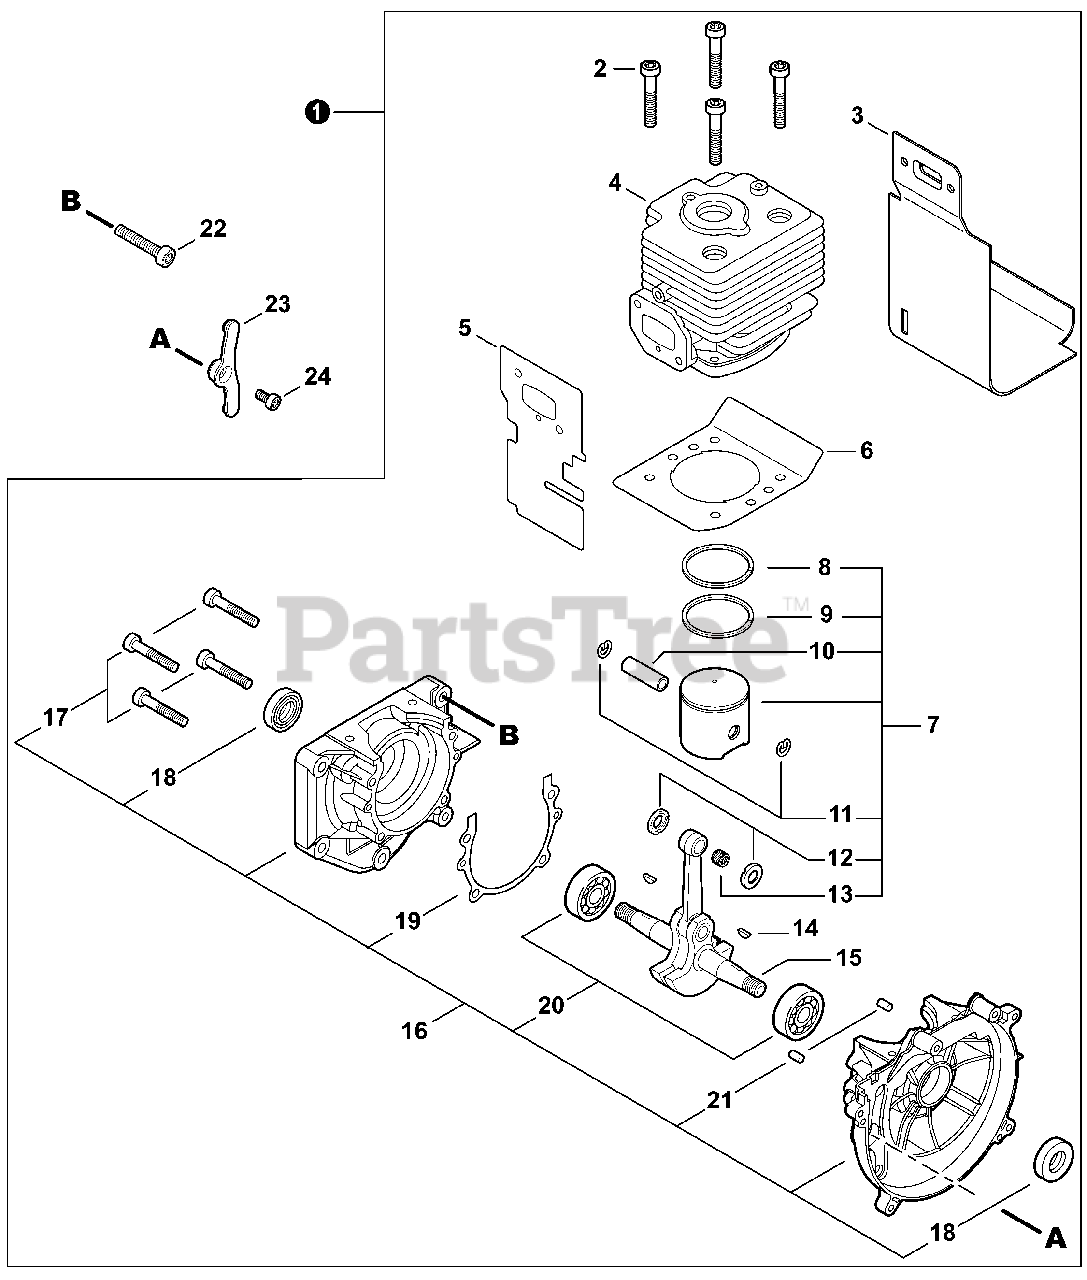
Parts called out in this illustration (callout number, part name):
1	SHORT BLOCK
2	BOLT, TORX 5×25
3	HEAT SHIELD, EXHAUST
4	CYLINDER
5	HEAT SHIELD, INTAKE
6	GASKET, CYLINDER
7	PISTON KIT
8	RING, PISTON
9	RING, PISTON
10	PIN, PISTON
11	RING, SNAP 8
12	WASHER, THRUST
13	BEARING, NEEDLE 10
14	KEY, WOODRUFF 3×14
15	CRANKSHAFT ASSY
16	CRANKCASE KIT
17	BOLT, TORX 5×30
18	SEAL, OIL 15
19	GASKET, CRANKCASE
20	BEARING, BALL 6302
21	PIN, LOCATING 4×8
22	BOLT, TORX 6×30
23	COVER, DUST
24	BOLT, TORX 5×10
